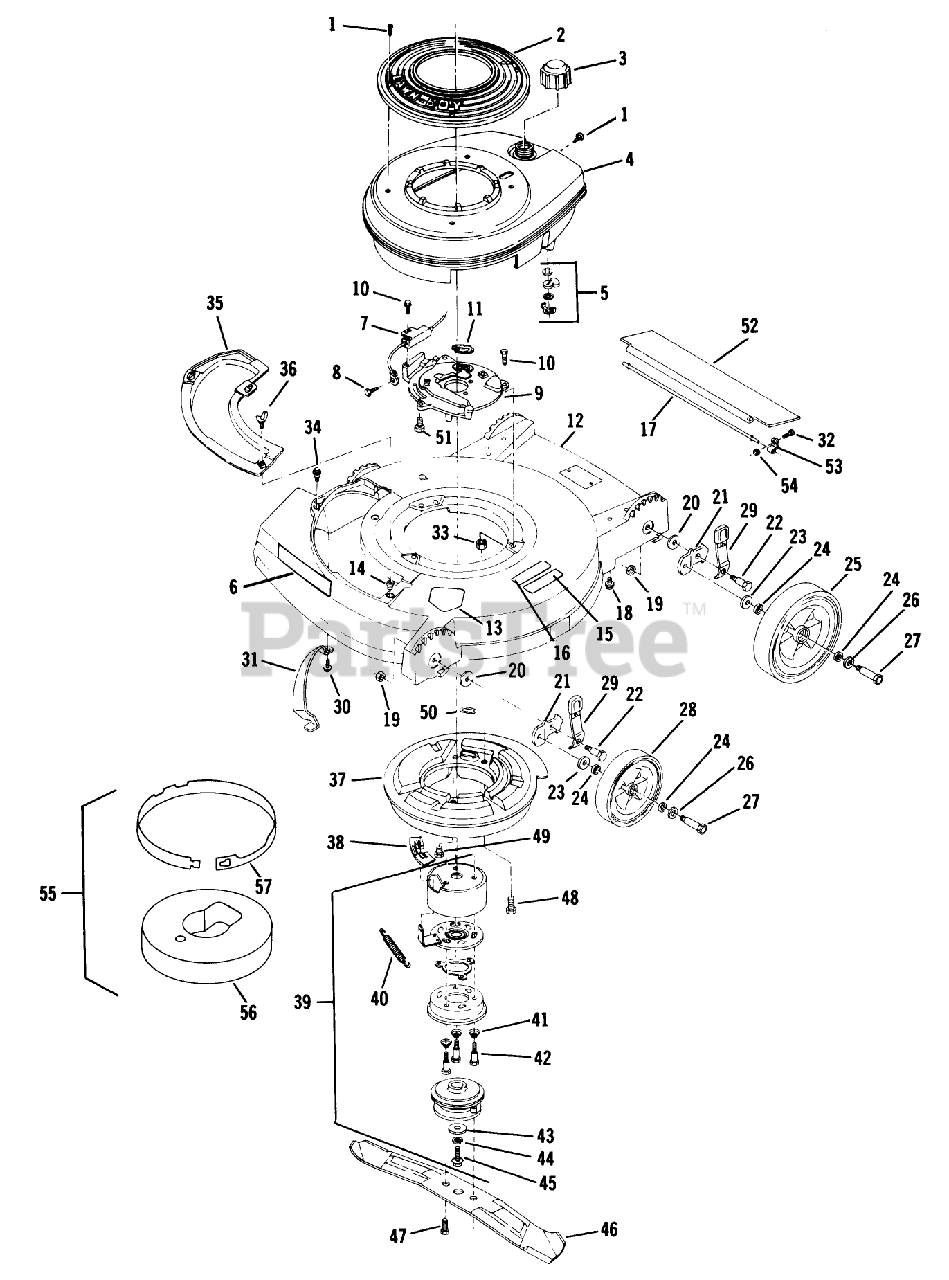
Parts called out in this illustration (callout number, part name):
1	SCREW - SELF TAPPING
3	FUEL CAP & INSERT
5	SHUT OFF VALVE KIT
10	SCREW-HH
15	PAD FOOT
17	ROD 21" ADVANCE
19	LOCKNUT
23	WASHER WROUGHT
27	BOLT WHEEL
28	WHEEL & TIRE KIT
31	BAR-TOE
33	NUT-LOCK F
36	WING SCREW LAWRE
42	SCREW,SHOULDER SM
47	SCREW SEMS
51	SCREW V
53	CLAMP ROD KMC
54	LOCKNUT E
